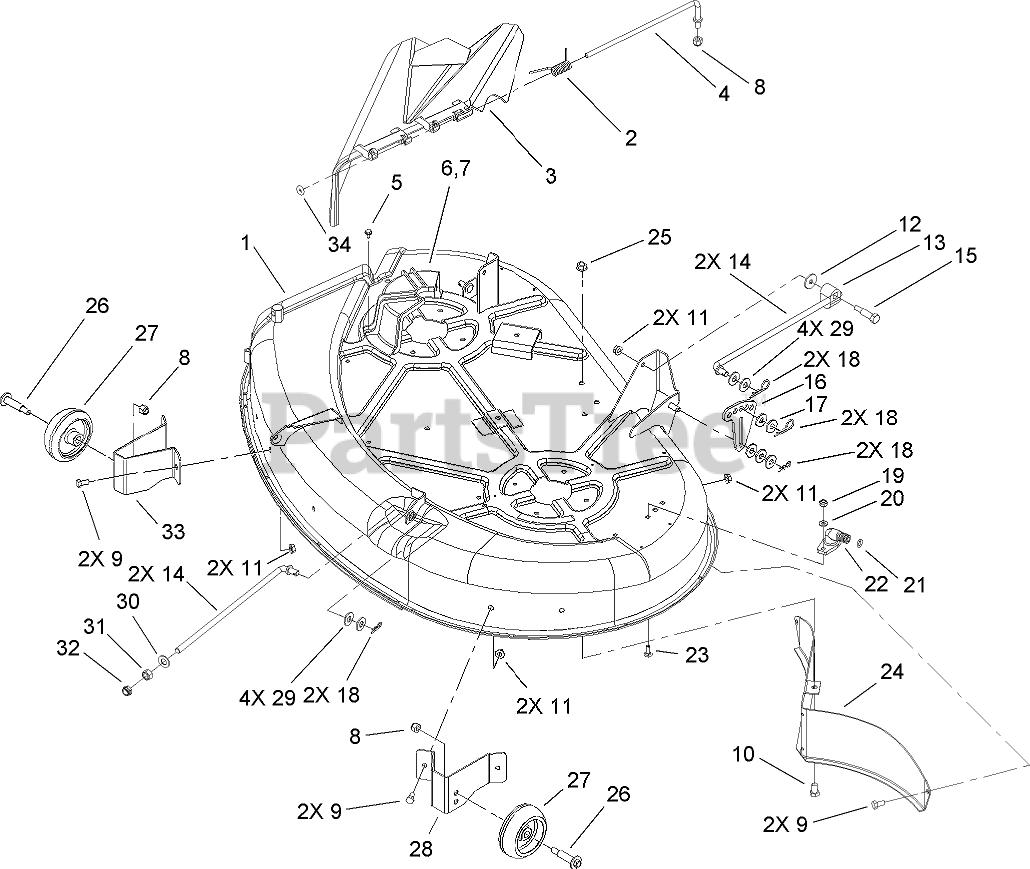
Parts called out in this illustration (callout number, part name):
1	42 INCH DECK ASM
2	SPRING
3	DEFLECTOR ASM
4	ROD-PIVOT
5	SCREW-HWHTF
6	GUIDE-BELT, LH
7	GUIDE-BELT, RH
8	NUT-LOCK, NI
9	SCREW-HH
10	SCREW-HH
11	NUT-HF
12	WASHER-PIVOT
13	TRUNNION-HOC
14	ROD-HANGER
15	SCREW-SHOULDER, HH
16	LINK-ADJUSTING, HOC
17	WASHER-HARDENED
18	PIN-HAIR
19	NUT-LOCK, NI
20	WASHER-FLAT
21	O-RING
22	FITTING-WASHOUT
23	BOLT-CARR
24	BAFFLE-REAR
25	NUT-HF
26	SCREW-SHOULDER, HWH
27	WHEEL-GAGE
28	BRACKET-GAGE WHEEL, FRONT (LH)
29	WASHER-FLAT
30	WASHER-FLAT
31	NUT-HEX
32	NUT-LOCK, NI
33	BRACKET-GAGE WHEEL, FRONT (RH)
34	O-RING
